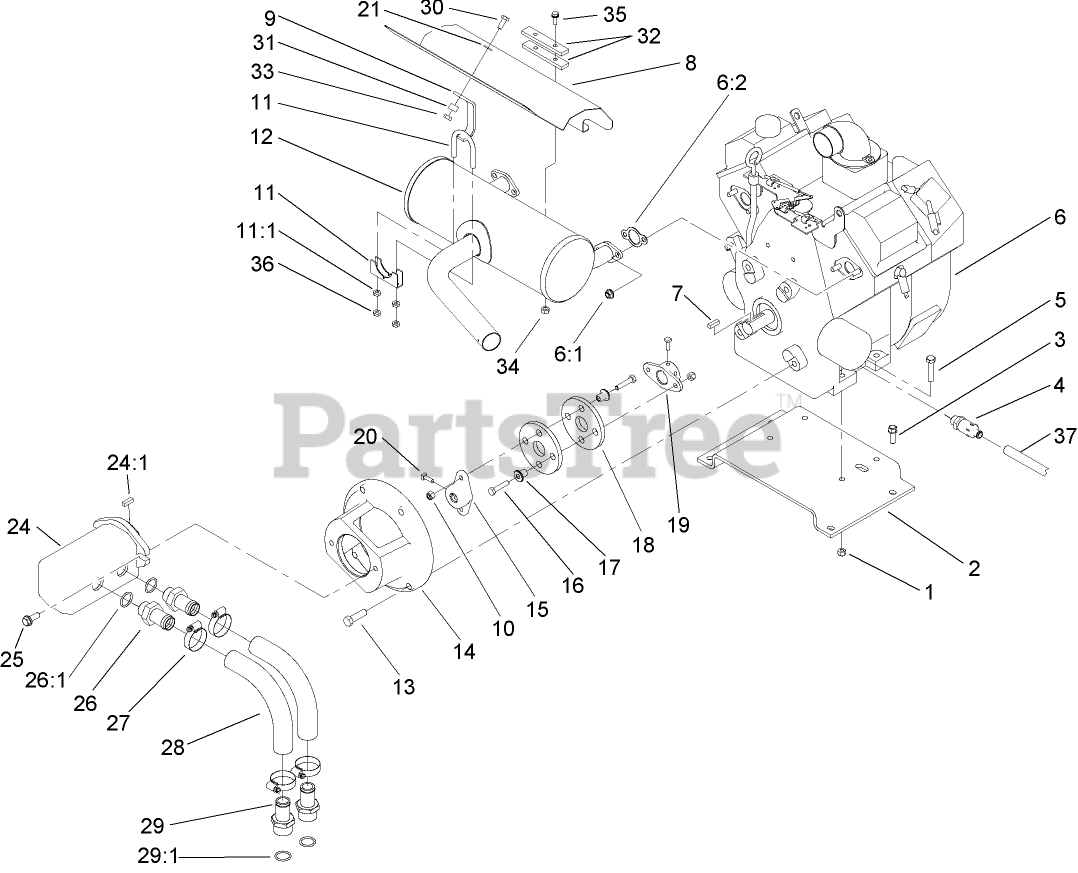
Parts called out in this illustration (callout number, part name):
1	NUT-LOCK, NI
2	MOUNT-ENGINE
3	SCREW-TAPTITE
4	VALVE-DRAIN, OIL
5	SCREW-HH
6:1	NUT-HF
6:2	GASKET-EXHAUST
7	KEY-SQUARE
8	SHIELD-MUFFLER
9	SUPPORT-SHIELD
10	NUT-LOCK, NI
11	CLAMP
11:1	NUT-HF
12	Muffler
13	SCREW-HH
14	MOUNT-PUMP
15	HUB-PUMP
16	SCREW-HH
17	SPACER
18	COUPLING-RUBBER
19	HUB-ENGINE
20	SCREW-SQH
21	WASHER-PLAIN
24	PUMP-GEAR, TANDEM
24:1	KEY-SQUARE
25	SCREW-HHF
26	FITTING
26:1	O-RING
28	HOSE-SUCTION, FORMED
29	FITTING-STR
29:1	O-RING
30	SCREW-HH
31	SPACER
32	SPACER-BAR
33	NUT-LOCK, CONE
34	NUT-LOCK, CONE
35	SCREW-HHF
36	NUT-JAM
